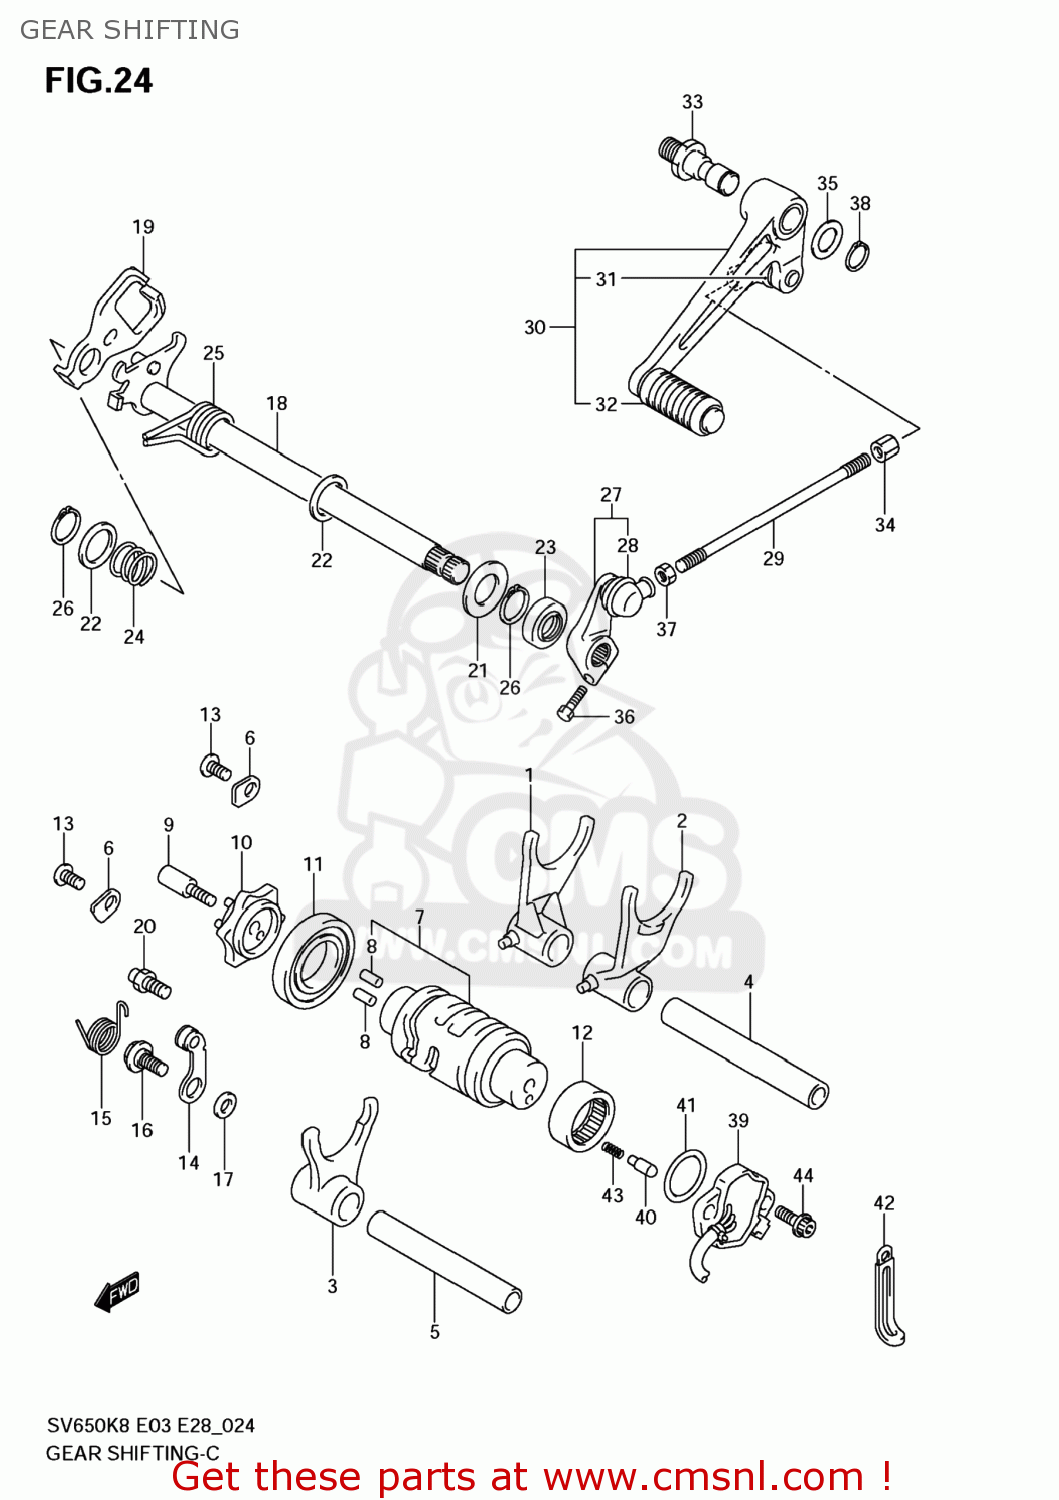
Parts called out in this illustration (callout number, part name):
1	FORK,GEAR SHIFT NO.1
2	FORK,GEAR SHIFT NO.2
3	FORK,GEAR SHIFT NO.3
4	SHAFT,GEAR SHIFT FORK
5	SHAFT,GEAR SHIFT FORK NO.1
6	RETAINER
7	CAM,GEAR SHIFT
8	PIN
9	BOLT,GEAR SHIF
10	PLATE,GEAR SHIFT CAM
11	BEARING(25X47X8)
12	BEARING(25X32X12)
13	SCREW
14	STOPPER,SHIFT CAM
15	SPRING,SHIFT
16	BOLT(6X14.3)
17	WASHER
18	SHAFT,GEAR SHIFT
19	PLATE,GEAR SHIFT CAM DRIVE
20	STOPPER,GEAR SHIFT ARM
21	WASHER(14X29X0.8)
22	SHIM(14X22X1)
23	SEAL,OIL(14X22X6)
24	SPRING
25	SPRING
26	CIRCLIP
27	ARM,GEAR SHIFT LINK
28	COVER,DUST
29	ROD,GEAR SHIFT LINK
30	GEAR SHIFTING LEVER
31	COVER,DUST
32	RUBBER,GEAR SHIFT PEDAL
33	SHAFT,GEAR SHIFT LEVER
34	NUT
35	WASHER(12.5X20X1)
36	BOLT
37	NUT
38	CIRCLIP
39	BASE ASSY,GEAR SHIFT TERMINAL
40	PIN(5X15.5)
41	O RING(D:2.4,ID:26.2)
42	CLAMP(L:80)
43	SPRING
44	BOLT
